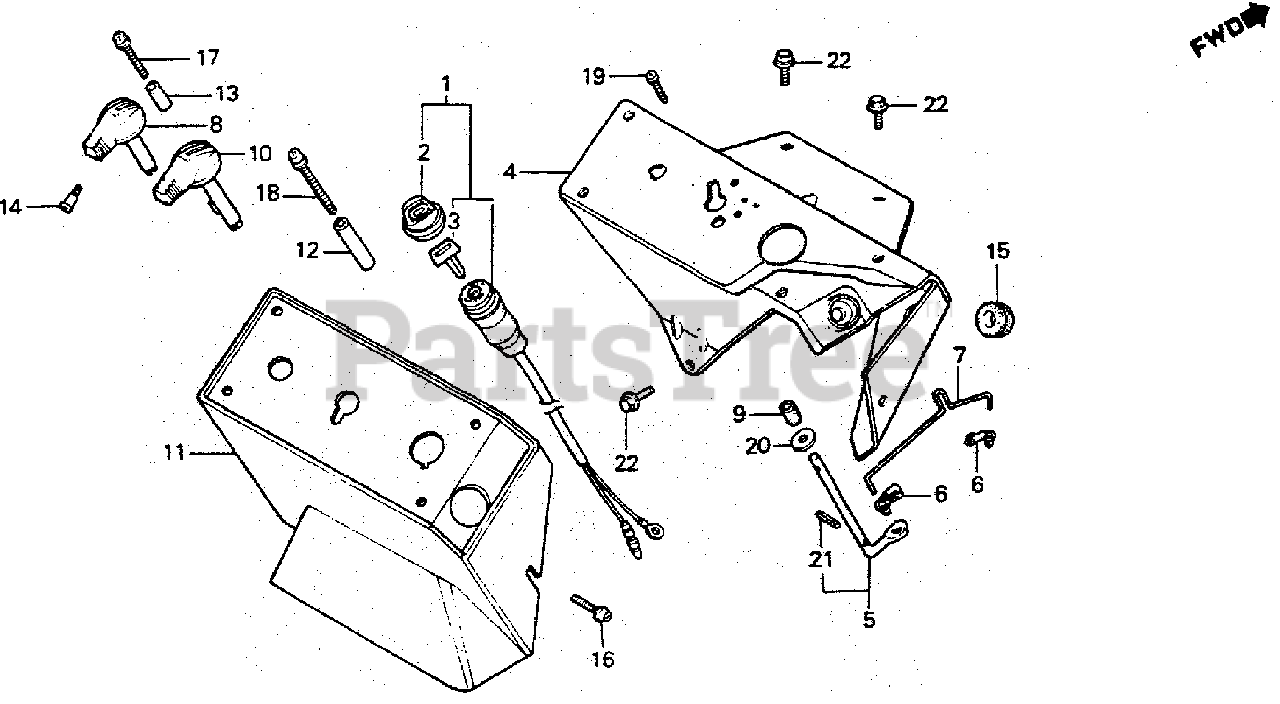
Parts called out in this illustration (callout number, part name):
1	LOCK SET (NOT AVAILABLE)
2	CAP, COMBINATION SWITCH KEY
3	KEY, BLANK (TYPE1)
3	KEY, BLANK (TYPE2)
4	PLATE, CONTROL
5	SHAFT, CHOKE CONTROL (NOT AVAILABLE)
6	JOINT, ROD
7	ROD, CHOKE (NOT AVAILABLE)
8	KNOB, CHOKE CONTROL
9	RUBBER, FRICTION (NOT AVAILABLE)
10	KNOB, CONTROL
11	PANEL, CONTROL (NOT AVAILABLE)
12	COLLAR A (NOT AVAILABLE)
13	COLLAR B (NOT AVAILABLE)
14	SCREW, CHOKE KNOB (3X11)
15	RUBBER, CONTROL BOX
16	SCREW-WASHER (5X16)
17	SCREW-WASHER (5X28)
18	SCREW-WASHER (5X45)
19	SCREW, TAPPING (3X12)
20	WASHER, PLAIN (6MM)
21	PIN, SPRING (2.5X12)
22	BOLT, FLANGE (6X10)
